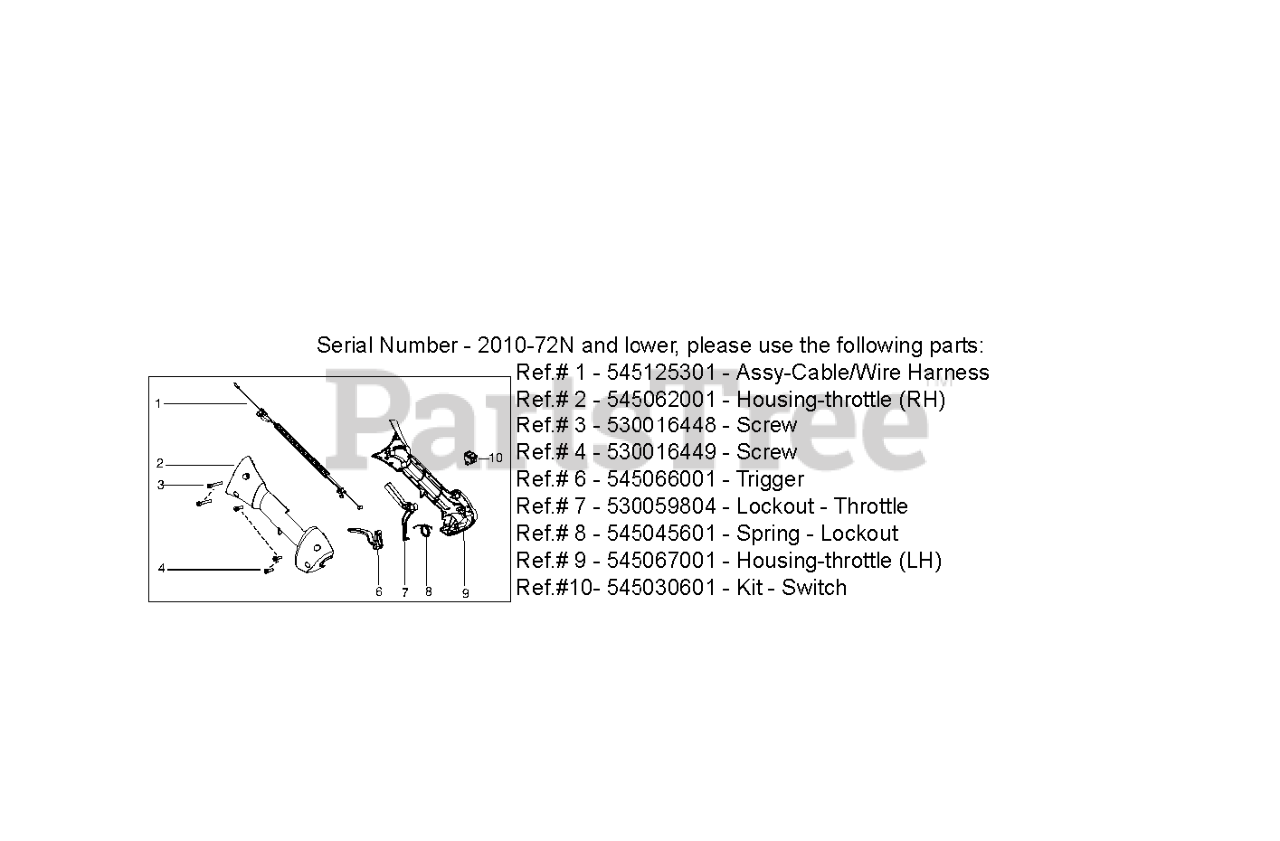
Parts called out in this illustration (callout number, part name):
1	ASSY-CABLE WIRE HARNESS
2	HOUSING-THROTTLE RH
4	SCREW M4 X 1.75 PT 16MM
6	TRIGGER THROTTLE
7	THROTTLE LOCKOUT
8	SPRING LOCKOUT
9	HSG THROTTLE LH
10	KIT SWITCH
